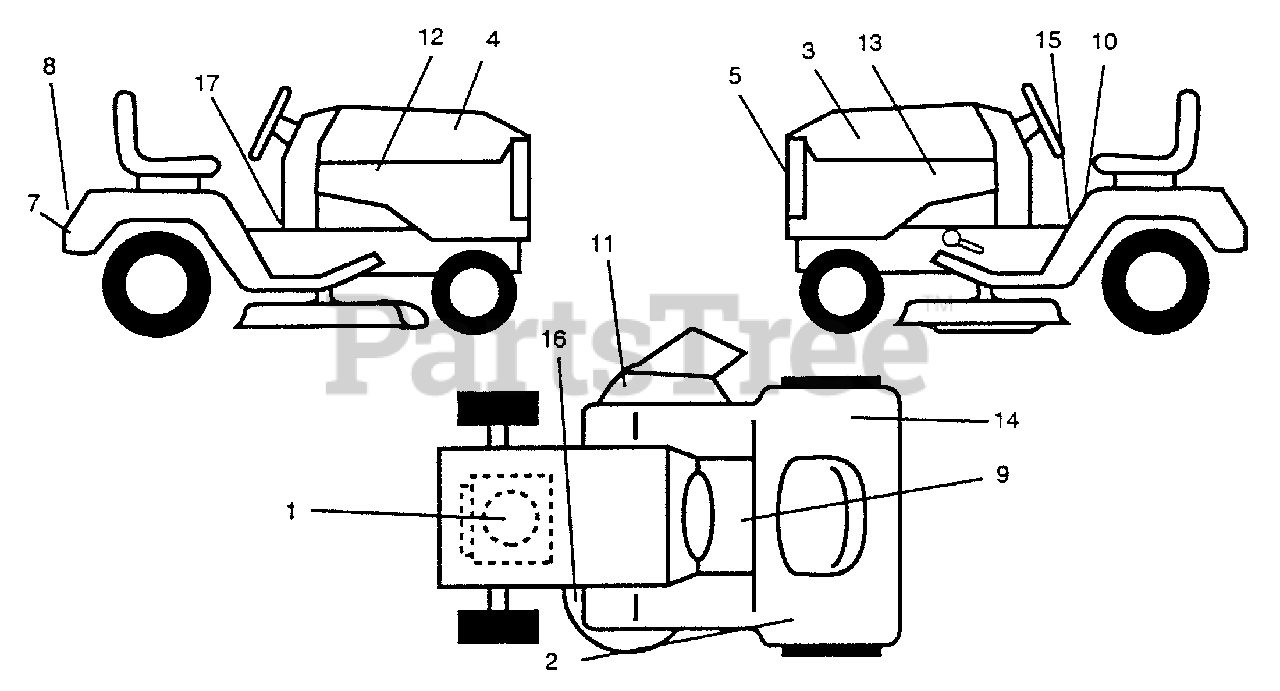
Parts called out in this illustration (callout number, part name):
1	Decal, Engine, B&S 13 hp Vang.
2	Decal, Indicator, Height
3	Decal, Hood, L.H.
4	Decal, Hood, R.H.
5	Decal, Logo, Grill
7	Decal, Drawbar
8	Decal, Logo, Fender
9	Decal, Cold Start
10	Decal, Fender, Caution
11	Decal, Warning, Multi-Language
12	Decal, Hood, Insert, R.H.
13	Decal, Hood, Insert, L.H.
14	Decal 80 DBA
15	Decal, Instruction, Operating
16	Decal, V-Belt Schematic
17	Decal Cold Start Hydro
CER38	Grass Catcher
